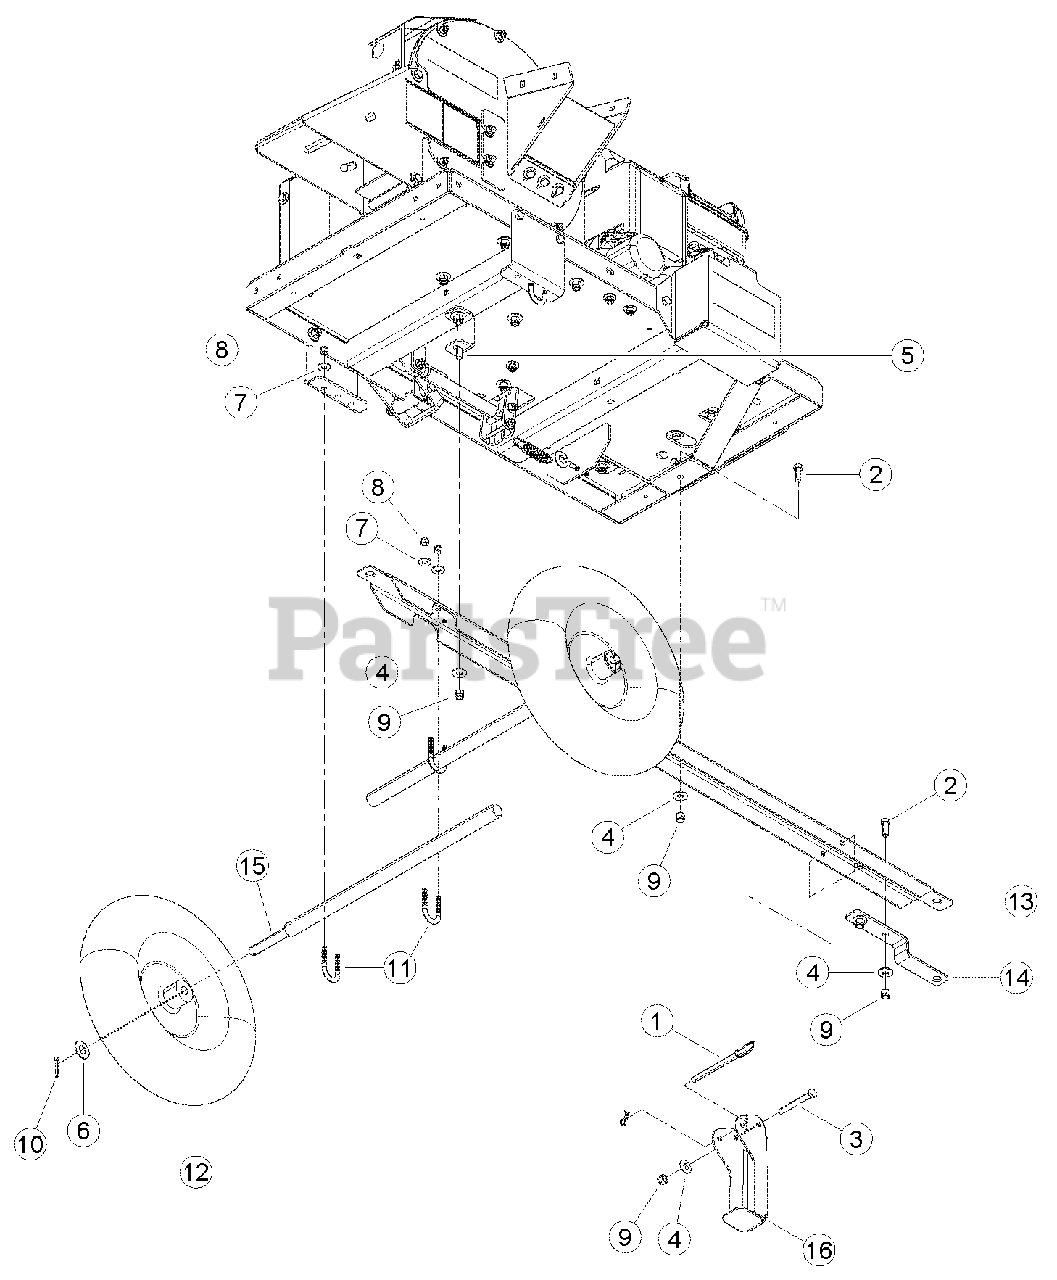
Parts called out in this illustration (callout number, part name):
1	PIN, 3/8 HITCH
2	BOLT, 3/8 X 1 HEX HD GR5 ZP
3	BOLT, 3/8 X 3 HEX HD GR5 ZP
4	WASHER, 3/8 FLAT ZP
5	BOLT, 3/8 X 1 CRG GR5 ZP
6	WASHER, 5/8 SAE FLAT ZP
7	WASHER, 5/16 FLAT ZP
8	NUT, 5/16 NE NYLOCK ZP
9	NUT, 3/8 NE NYLOCK ZP
10	PIN, 3/16 X 1-1/4 COTTER
11	U-BOLT, 5/16 X 1.0 X 2-3/16
12	TIRE, 480/400 X 8 WHEELBARROW
13	POLE, L + G HITCH
14	PLATE, HITCH POLE
15	AXLE, L + G
16	STAND, JACK
